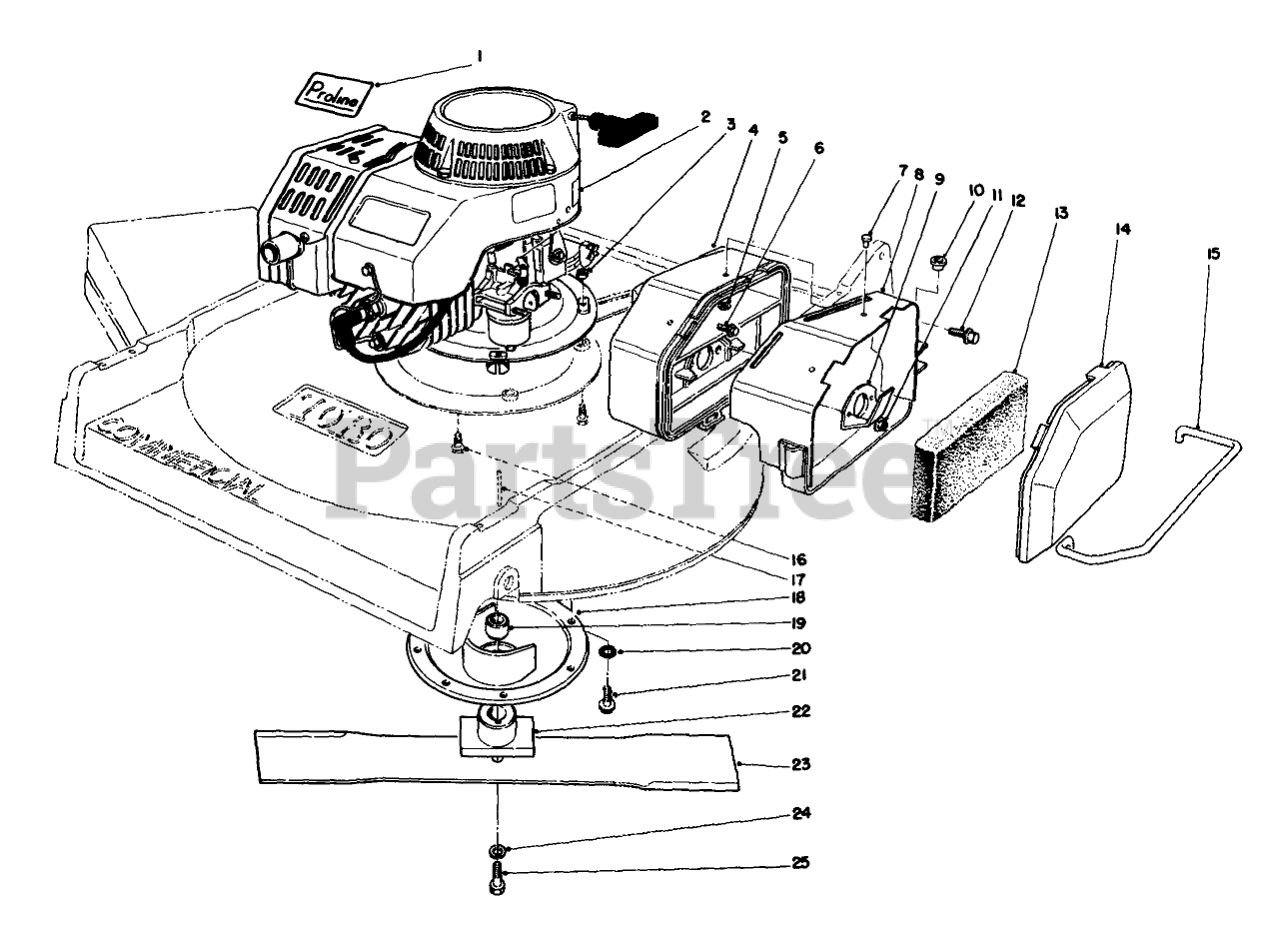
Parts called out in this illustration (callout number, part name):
1	DECAL - PROLINE
2	DECAL - FUEL
3	NUT-JAM
4	Air Cleaner Assembly (Incl. Ref. #5, 7 & 8)
5	WASHER-FLAT
6	HEX FL HD M.6X1.0X25MM
7	RIVET-POP
8	AIR CLEANER COVER WA
9	SPIT BACK DEFLECTOR
10	5/16 ID BSHG
11	NUT-LOCK
12	SCREW-HHF
13	FILTER
14	AIR CLEANER COVER
15	AIR CLEANER GUARD
16	SCREW-HH
17	KEY-SQUARE
18	PROTECTOR-CRANKSHAFT
19	BLADE SPACER
20	WASHER-LOCK, INTERNAL
21	SCREW-HWHTF
22	BLADE RETAINER WA
23	BLADE
24	WASHER-LOCK
25	SCREW-BLADE
